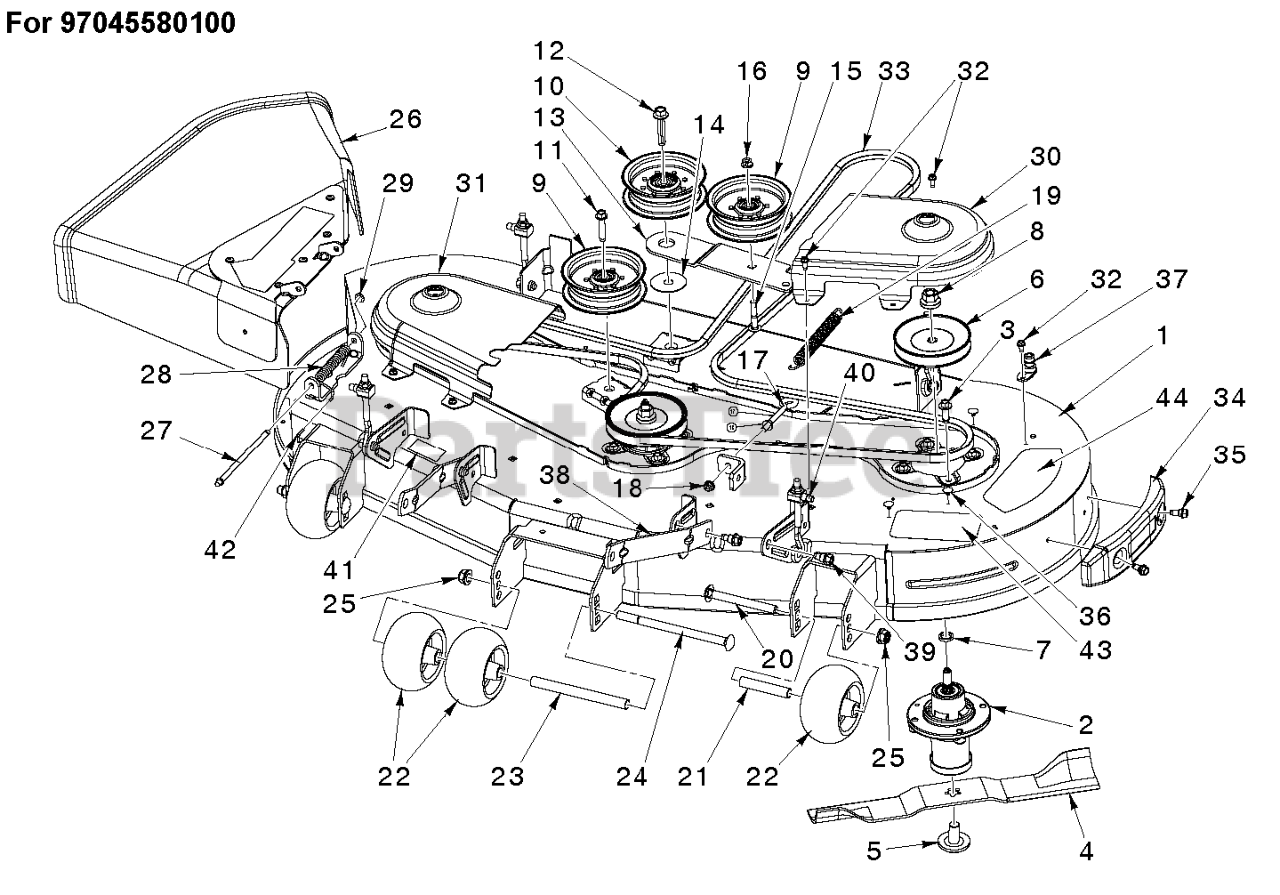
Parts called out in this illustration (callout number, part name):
1	DECK.SVC.54.CLRCT.MZ.MS668
2	MANDREL.DECK.ASSEMBLY
3	BOLT.HEX.WASHR.HED.313-18X1.19
4	BLADE.54CC.HI-LIFT.PZ.197".431
5	BLADE BOLT/WASHER
6	PULLEY.MANDREL.CRD 107CM.DOM.
7	WASHER.SPACER.MANDREL
9	PULLEY.IDLER.2006
10	PULLEY.IDLER.MWR.STATI.LH
11	BOLT;HEX_3/8-16 X 1.78.CLRZINC
12	SCREW.7/16-14 X 2.125.WASHER
13	ARM IDLER ARM, CLEARCUT 54 BLA
16	NUT.HEX.FLANGE.3/8-16.LOCKNUT
17	GSPW Bolts
18	GSPW Hardware
19	SPRING.MOWER.DRIVE.ELECTRIC
22	ROLLER, GAUGE .635 BORN
25	NUT 1/2-13 HEX FLANGE NYLOK CL
26	DEFLECTOR ASSY 54 CLEARCUT RES
27	ROD.HINGE
28	SPRING.42.FCS.DEFLECTOR
29	NUT PUSH M
30	COVER.PNT.54CC.MNDRL.LH.ZTR.GY
31	COVER 54 CLEARCUT RH MANDREL G
32	SCREW.1/4-20X5/8
33	Belts
34	BUMPER ASSY 54 CLEARCUT TRIM S
35	SHOULDER BOLT 5/16-18TT
36	PLUG CHRISTMAS TREE
37	PORT.WASHOUT
38	ARM.RFIXED.MOWER.SUSPNSIONX431
39	BOLT.SHOULDER
40	NUT NUT.3/8-16.HEX.JAM.Z 3/8-1
40	LINK.ASM.ADJUSTABLE
41	DECAL BELT ROUTING DECAL DECAL
42	CAP-SLEEVE LT
44	DECAL DECK DECAL DECAL.54DECK.
